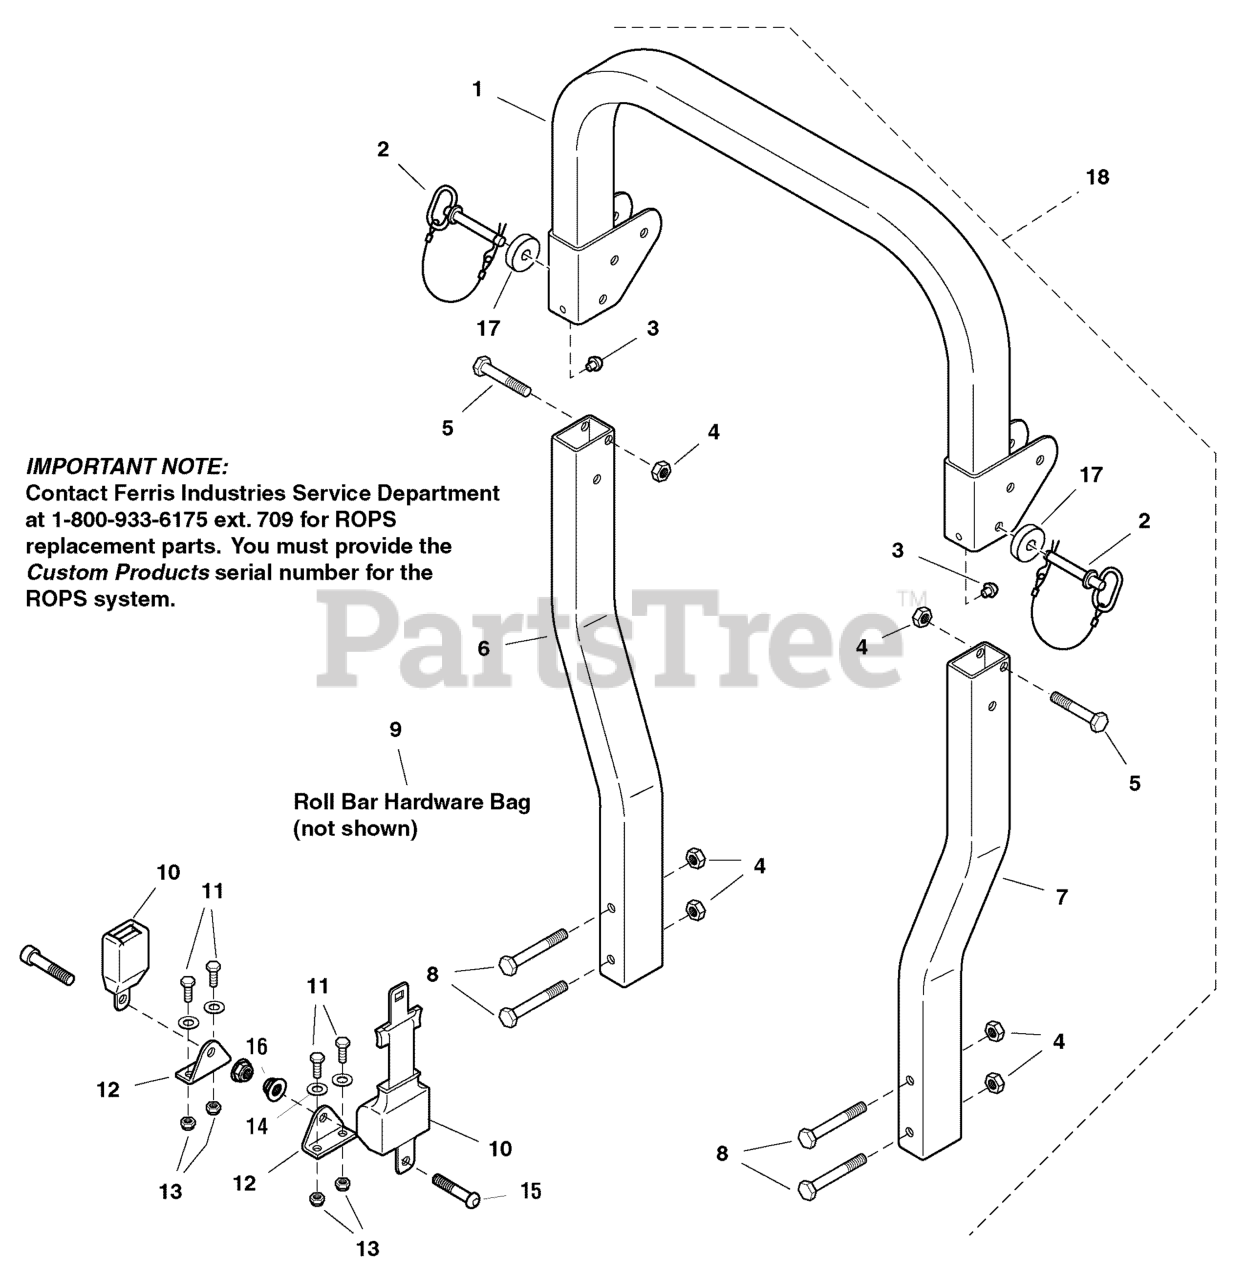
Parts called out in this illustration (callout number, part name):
1	ROLL BAR TOP LOOP
2	PIN, Hitch, Black W/ Plastic Lanyard
3	RUBBER BUMPER
4	* NUT
5	* BOLT
6	ROLL BAR POST, RH
7	ROLL BAR POST, LH
8	* BOLT
9	ROLL BAR HARDWARE BAG
10	SEAT BELT ASSEMBLY, Standard
10	SEAT BELT ASSEMBLY, Extra Long
11	BOLT, 3/8-16 X 1" GD5 CZ
12	MOUNT, SEAT BELT - RED
13	NUT, 3/8-16 Hex Nylock Flange
14	WASHER, 3/8 SAE
15	SCREW, 1/2-13 X 1" SHCS
16	NUT, Hex Flange, Nylock, 1/2-13
17	RUBBER WASHER
18	ROPS (Call 1-800-933-6175 ext. 2193 if replacing a ROPS)
